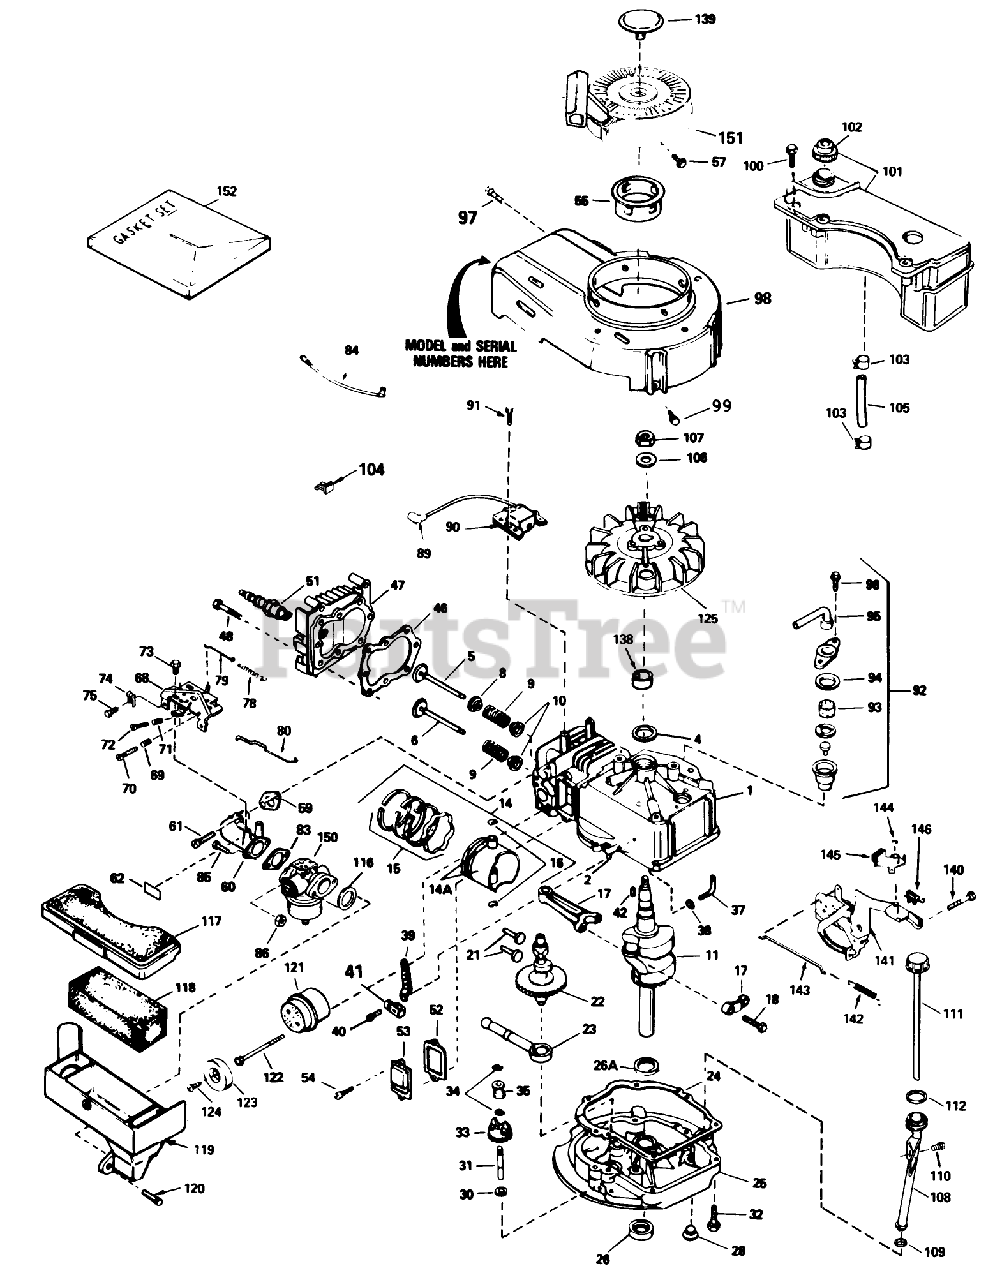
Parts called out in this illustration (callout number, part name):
1	Cylinder Assy. (Incl. #24)
2	Pin-Dowel
4	Seal-Oil
5	Valve, Intake (Std.) (Incl. Ref. #40)
5	Valve, Intake (1/32" oversize)(Incl. No. 40)
6	Valve, Exhaust (Std.)(Incl. No. 40)
6	Valve, Intake (1/32" oversize)(Incl. No. 40)
8	Seal Assy., Intake
9	Spring-Valve
10	Cap-Valve, Spring
11	Crankshaft
14	Piston-Pin Ring Assy. (Std.)(Incl. Ref. #16A, 17 18)
14	Piston-Pin Ring Assembly (.010 oversize)(Incl. Ref. #16A, 17 18)
14	Piston, Pin Ring Assy. (.020 Oversize)(Incl. Ref. #13A, 14, 15)
14A	Piston Pin Assy. (Std.)(Incl. Ref. #14)
14A	Piston Pin Assembly (.010 oversize)(Incl. Ref. #18)
14A	Piston Pin Assy. (.020 Oversize) (Incl. Ref. #14)
15	Ring Set-Piston (Std.)
15	Ring Set, Piston(.0100versize)
15	Ring Set (.020" OS)
16	Ring-Retaining, Piston Pin
17	Rod Assy., Connecting (Incl. Ref. #17)
18	Bolt-Rod, Connecting
21	Lifter-Valve
22	Camshaft(Mech.Comp. Release)
23	Oil Pump ASM
24	Gasket
25	Flange-Mounting (Incl. Ref. #26, 27 39)
26	Seal-Oil
26A	Washer-Thrust
28	Plug Oil Drain
30	Washer-Flat
31	Shaft-Governor
32	Screw (1/4-20 x 1-1/4)
33	Governor Gear ASM
34	Ring-Retaining
35	Spool-Governor
37	Rod, Governor (Incl. No. 36)
38	Washer-Flat
39	Governor Lever
40	Screw
41	Clamp-Lever, Governor
42	Key-Flywheel
46	63573 GIL 42 SNWTHW
47	Head-Cylinder
48	Screw (5/16-18x1-1/2)
51	Spark Plug-Resistor (R J19 L M)
52	Gasket-Breather
53	Cover-Valve
54	Screw
55	Hub-Starter
57	Screw, Hex Hd.
59	Gasket-Intake
60	Pipe-Intake (Incl. Ref. #59)
61	Screw (1/4-20 x 1)
62	Decal-Primer
68	Control Assy.-Remote Speed (Incl. Ref. #69 thru 72 76)
69	61709/GIL1515A/95-5
70	Screw
71	Spring-Compression
72	Screw
73	Screw (10-24 x 9/16)
74	Conduit
75	Screw (10-32 x 3/8)
78	Spring Governor
79	2035A67 ADD.ASSEMBL
80	Link-Throttle
83	Gasket
84	Ground Wire
86	Nut and Lock Washer (1/4-28)
89	Cover-Spark Plug
90	Solid State
91	Screw
92	Breather Assy. (Incl. Ref. #46 thru 51)
93	Element-Breather
94	Gasket-Breather
95	Tube, Breaker
96	Screw (10-24 x 9/16)
97	Screw (10-24 x 9/16)
98	Housing-Blower
99	Screw (1/4-20 x 1/2)
100	Screw (10-32 x 35/64)
101	Tank Assembly-Fuel (Incl. Ref. #102)
102	Cap-Fuel
103	Clamp-Line, Fuel
104	Clip-Wire
105	Line-Fuel
106	Washer-Belleville
107	Nut-Flywheel
108	Oil Fill Tube
109	Gasket
110	Screw (10-32 x 1/2)
111	Dipstick
112	O-Ring
116	Gasket-Cleaner, Air
117	Cover Air Cleaner
118	Filter-Air Cleaner
119	Body Air cleaner
120	Screw
121	Muffler (Incl. Ref. #122)
122	Screw
123	Cover-Muffler
124	Screw (8-32 x 3/8)
125	Flywheel
138	Spacer
139	Plug Starter
140	Screw (1/4-20 x 3/8)
141	Bracket-S.E. Brake
142	Spring-Extension
143	Link-Control
144	Ring-Retaining
145	Lever-Brake
146	Terminal
150	Carburetor (Incl. Ref. #83)
151	Starter-Rewind
152	Gasket Set
